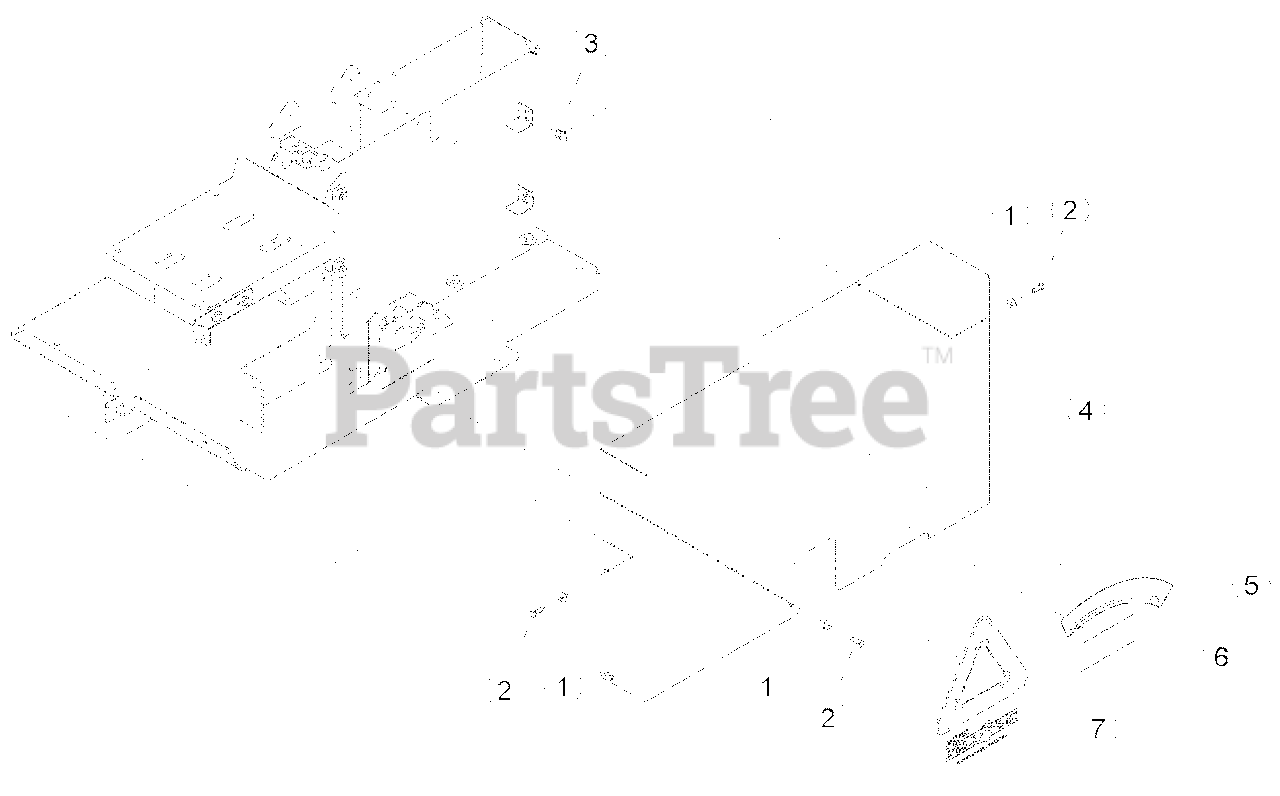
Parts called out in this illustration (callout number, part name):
1	WASHER, 5/16 FLAT ZP
2	BOLT, 5/16 X 7/8 HHCS GR5 NC ZP
3	NUT, 5/16-18 TINNERMAN U-TYPE
4	ASSEMBLY, CHIPPER SHIELD W/DECALS, SERVICE PART
5	DECAL, START/ENGAGE
6	DECAL, MUTILINGUAL MANUAL
7	DECAL, CHIP IT LARGE
